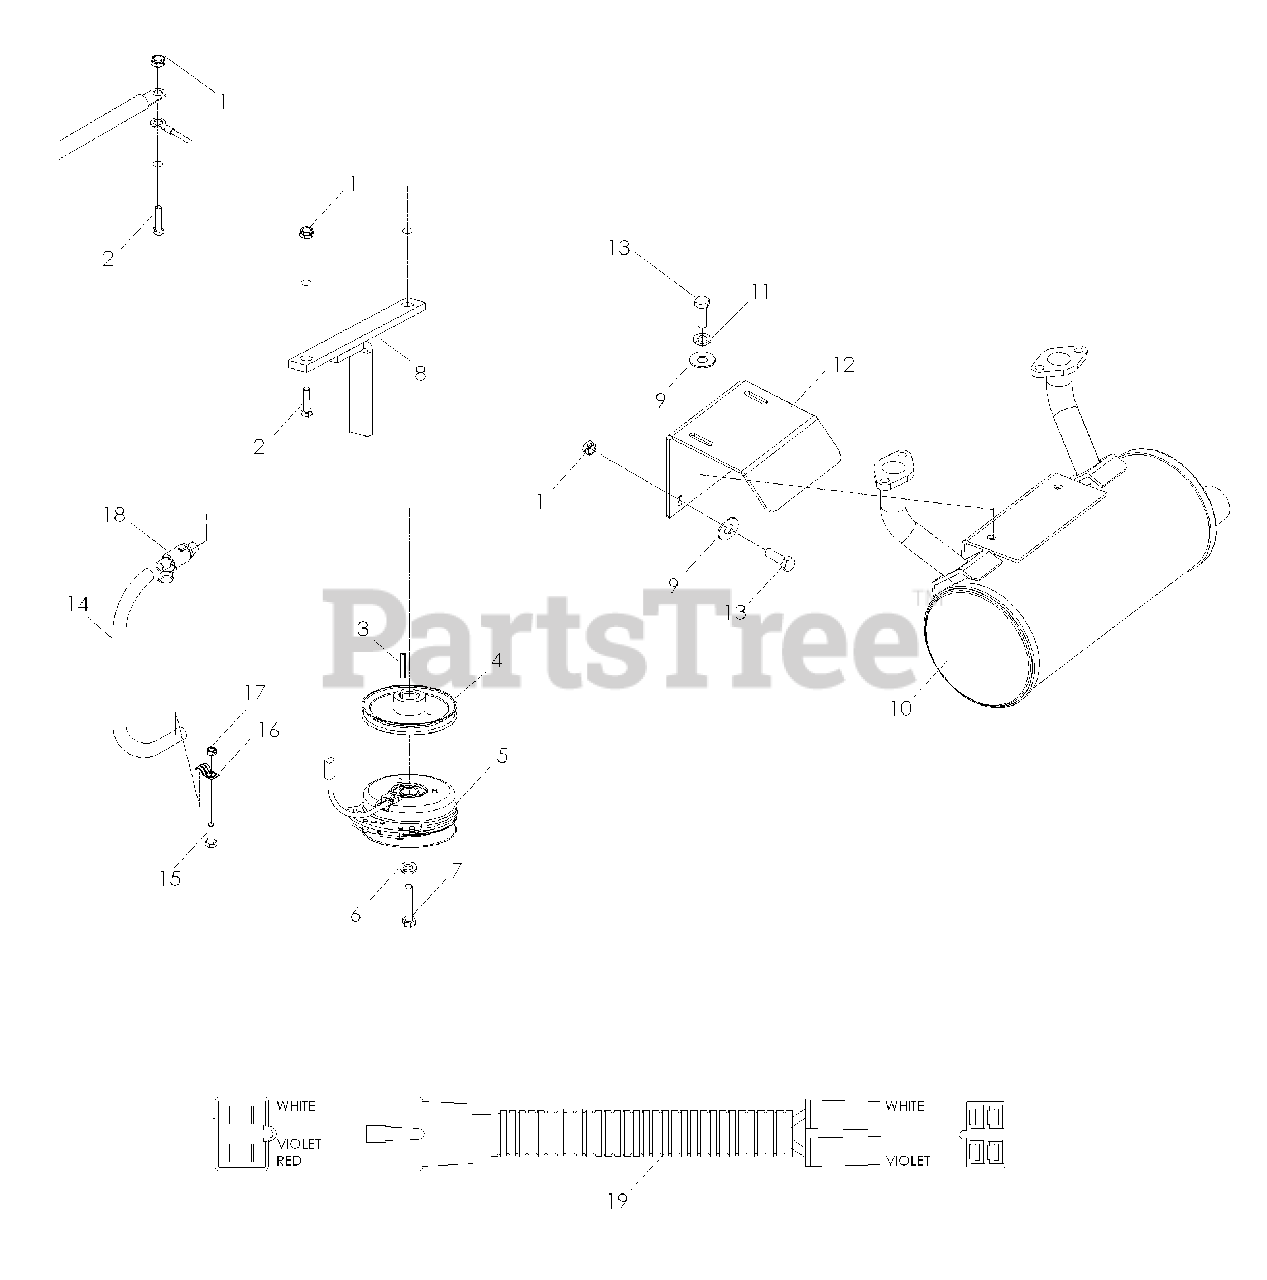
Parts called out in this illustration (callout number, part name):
1	NUT 5/16-18 HEX NYLOC
2	HCS 5/16 x 1 3/4
6	WASHER, 7/16 LOCK
7	HCS 7/16 x 2 1/2
8	CLUTCH TIE DOWN
9	WASHER, 5/16 FLAT
11	LOCK WASHER 5/16
12	BRACKET MUFFLER
13	HCS 5/16-18 x 1
14	OIL DRAIN HOSE
15	HCS 1/4-20 x 3/4
17	NUT 1/4-20 CNTRLOCK
18	OIL DRAIN FITTING
